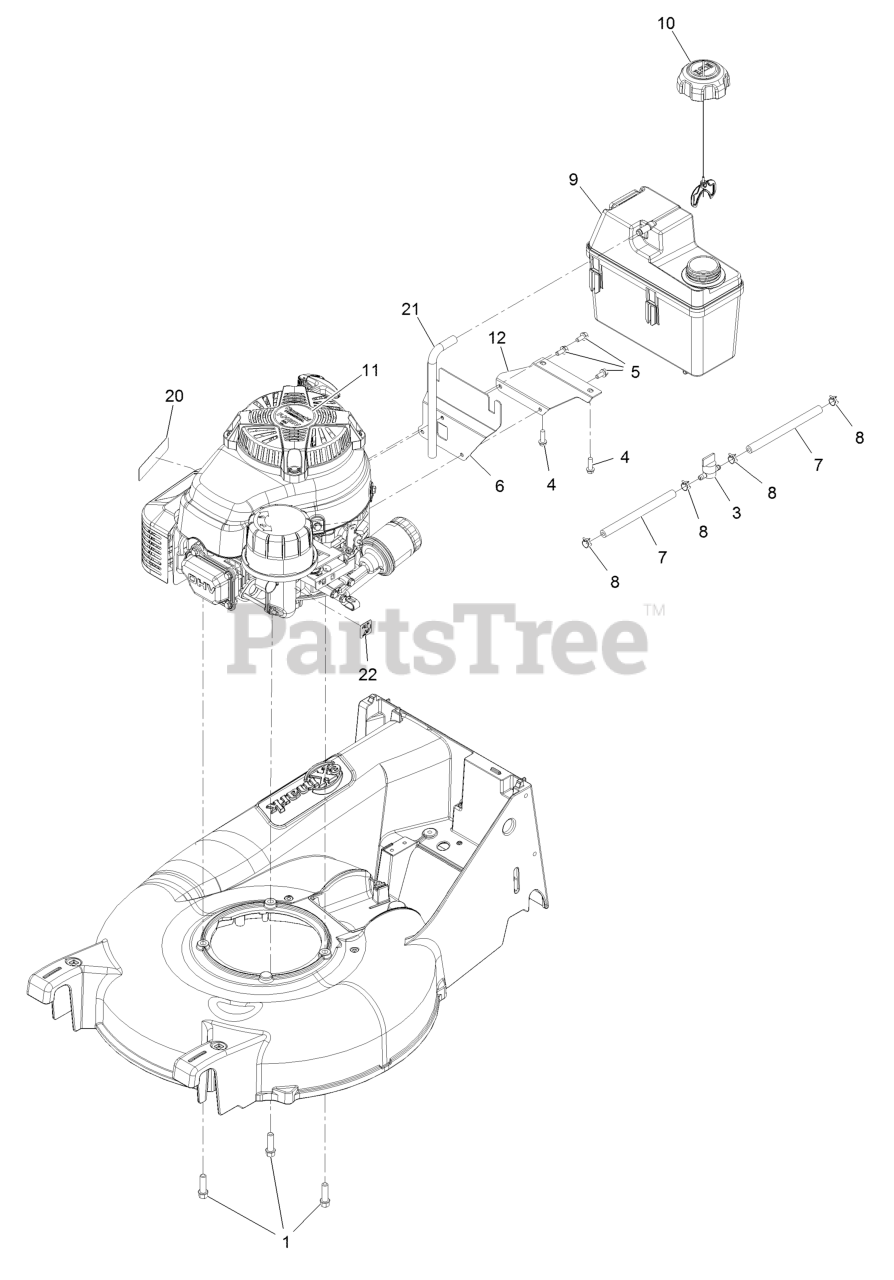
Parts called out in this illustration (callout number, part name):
1	Screw-HWH 3/8-16 X 1 1/4 Taptite
3	Valve-Fuel
4	Screw-HWH 1/4-10 X .82 Plastite
5	Screw-HWH
6	Bracket-Tank, Mounting
7	Hose-Fuel
8	Clamp-Hose
9	Tank-Fuel
10	Cap-Fuel
11	Decal-Recoil
12	Bracket-Tank, Support
20	Decal-Arrester, Spark
21	Hose-Vent, Canister
22	Decal-Primer
